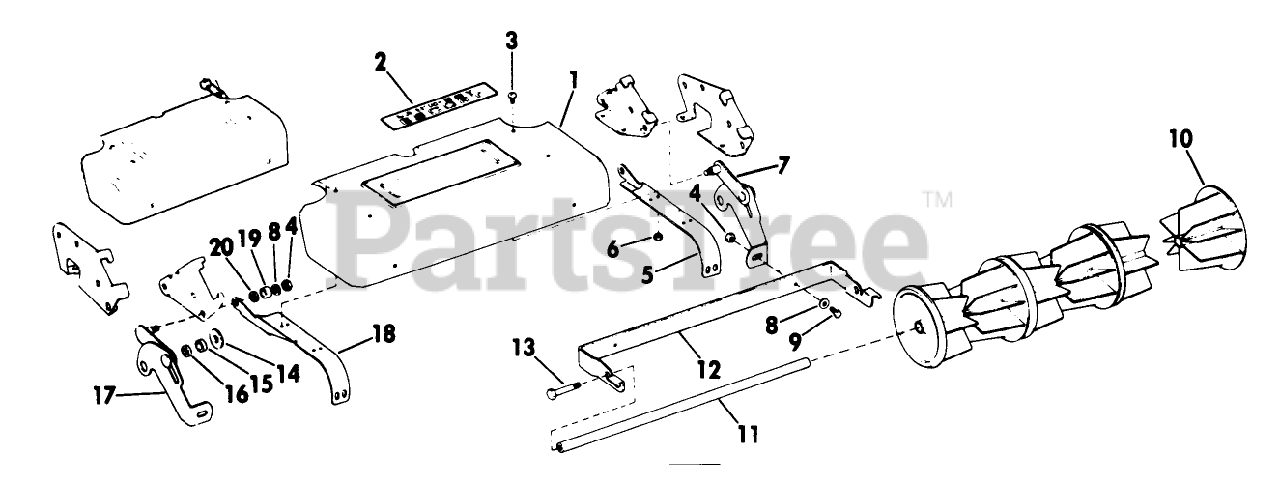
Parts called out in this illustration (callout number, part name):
1	Roller Cover Decal Assembly
14	WASHER WROUGHT
15	Spacer-Wheel-Red
17	Roller Link Assembly-Right
